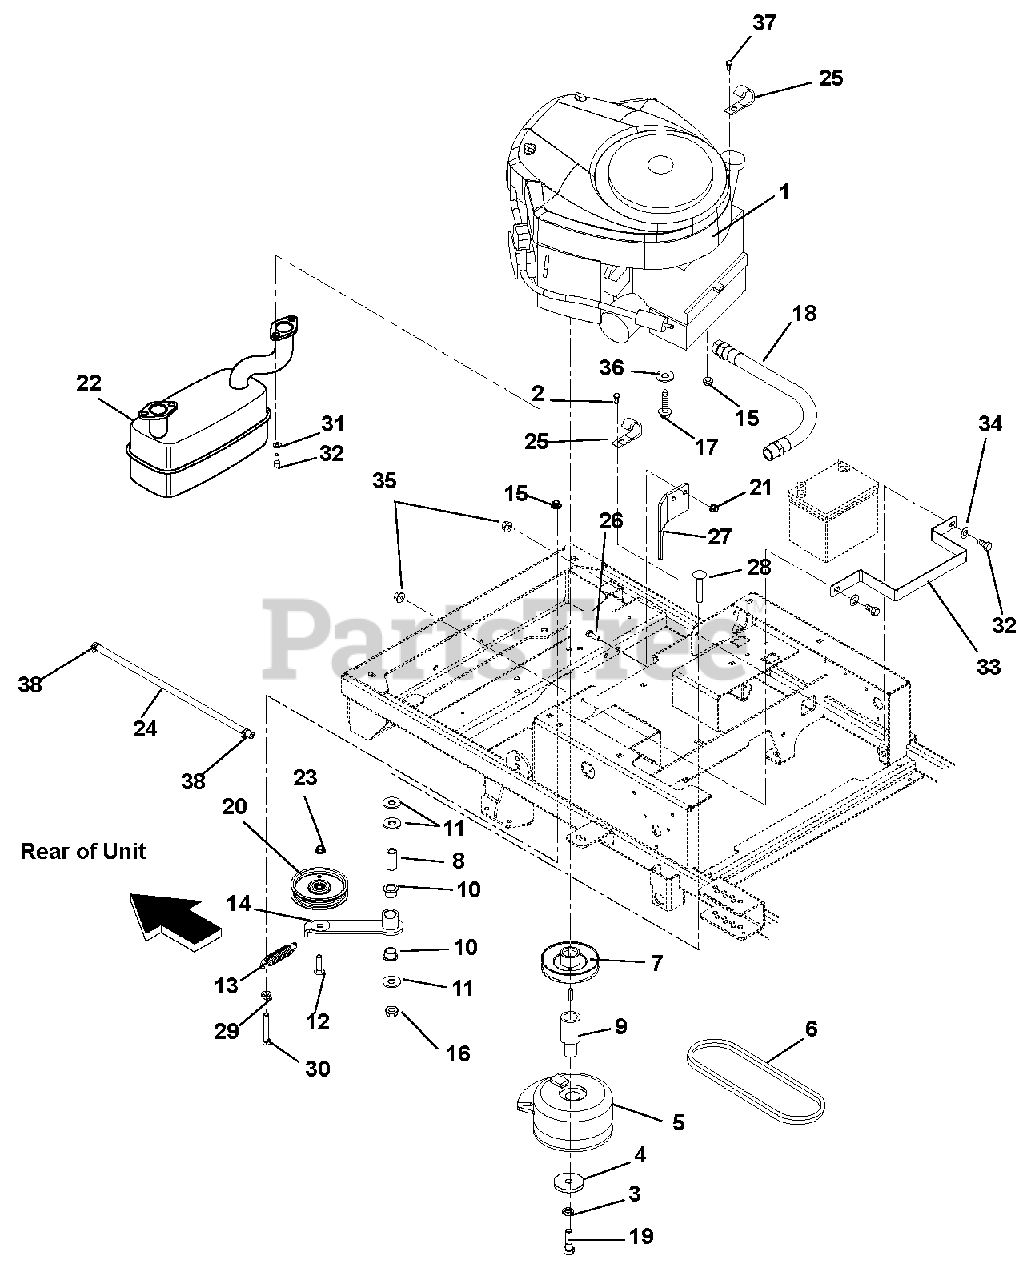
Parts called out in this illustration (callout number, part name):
1	Engine, Kawasaki FR691V (915160)
2	Screw, Tapping .250-20 x .37 Hex Washer Head
3	Washer, Locking .44 x .109 Regular
4	Washer, Flat Steel .469 x 2.00 x .25
5	Clutch, XL
6	Belt, HA 62.50 Wrapped
7	Pulley, V 4.5 x 1.5 AB Section with Key
8	Bushing, Sleeve .500 x .750 x 1.560
9	External, Crankshaft Lower
10	Bushing, Flange 0.75 x 0.875 x .625 x 1.125
11	Washer, Flat Steel .563 x 1.38 x .109
12	Bolt, Round Head Square Neck .38-16 x 1.50 Grade 5
13	Spring, Tension .105 x .812 x 3.88
14	Weldment, Ground Drive Idler Arm
15	Nut, 3/8-16 Flange Nyloc
16	Nut, Locking Top Flange .50-13
17	Bolt, Hex .38-16 x 1.25
18	Hose Assembly, Oil Drain
19	Bolt, Hex .44-20 x 4.50 Grade 8
20	Assembly, 4" Idler
21	Nut, .31-18 Nyloc Flange
22	Muffler, Kawasaki Twin Courage
23	Nut, Locking Top Flange .38-16
24	Fuel Hose
26	Bolt, Hex .31-18 x 1.00 Grade 5
27	Clutch Stop
28	Bolt, Round Head Square Neck .50-13 x 2.50 Grade 5
29	Nut, Flange .375-16
30	Bolt, Hex .38-16 x 2.50 Grade 5
31	Washer, Locking .31 x .078 Regular
32	Bolt, Hex .25-20 x .75
33	Bracket, Battery Hold Down
34	Washer, Flat Steel .281 x .62 x .065
35	Nut, KEPS .250-20
36	Washer, Flat-Steel .406 x .812 x .065
37	Bolt, Hex .38-16 x .75 Grade 5
38	Clamp, Fuel Line
